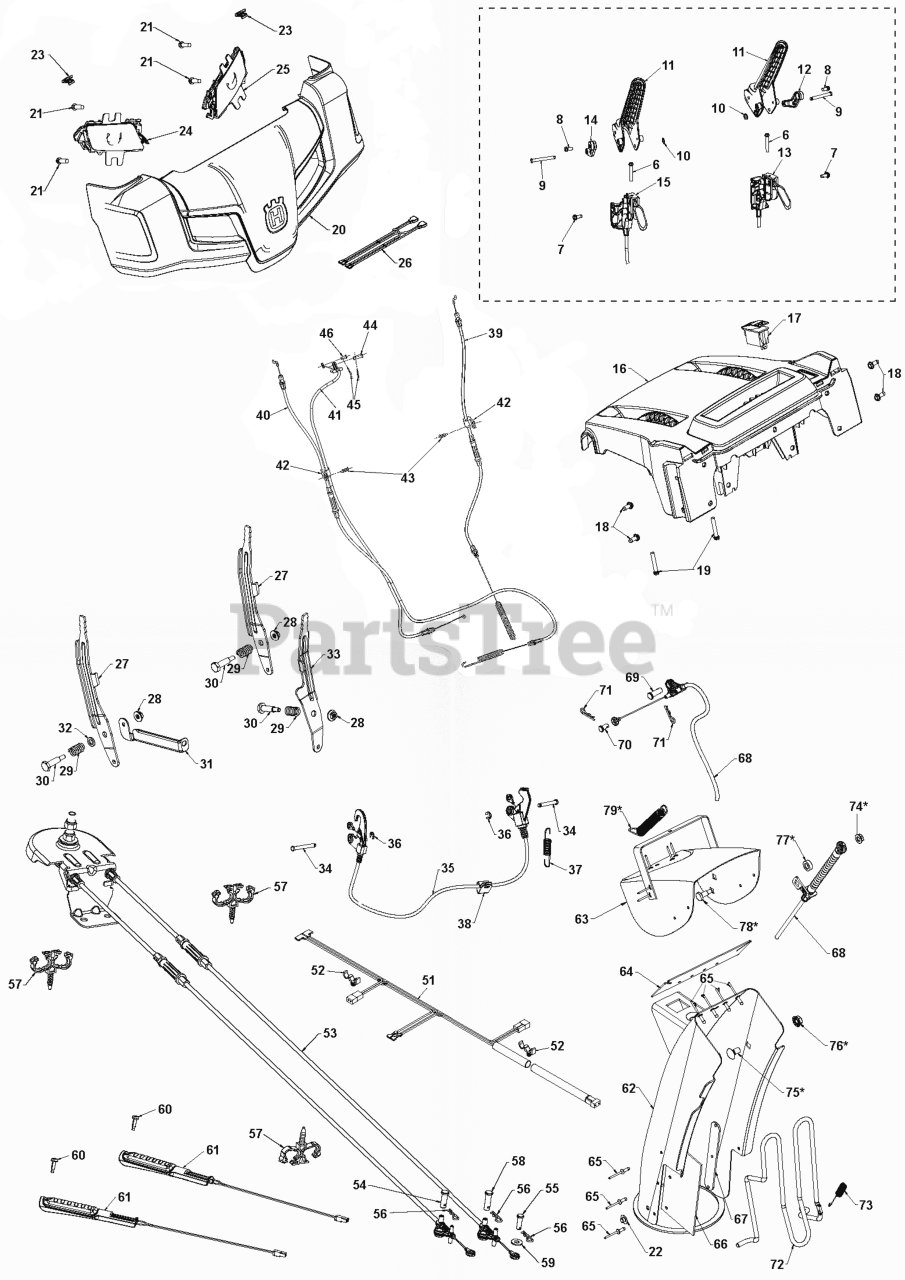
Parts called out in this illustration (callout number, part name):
6	SCREW HEX_WASH_13-16 X 1.50_H
7	SCREW 14-20 X 5/8
8	SCREW.HWH.13-16X.50
9	PIN.GROOVED
11	LEVER CONTROL DSST OPP MPP
12	LEVER.CABLE.ARM.RHS.BLACK
13	CABLE.POWER STEERING.RHS
14	LEVER.CABLE.ARM.LHS.BLACK
15	CABLE.POWER STEERING.LHS
16	CONSOLE.BASE.MULTICONT.498SWIT
17	SWITCH HEATED GRIP BLK
18	SCREW 14-20 X 5/8
19	SCREW HEX_WASH_13-16 X 1.50_H
20	COVER CONSOLE_ASM_HUSQVARNA
21	SCREW.HWH.13-16-5.8.BZP
22	NUT
23	CLIP PANEL ERGO 30603
24	LIGHT ASM.HUSQVARNA.RH
25	LIGHT ASM.HUSQVARNA.LH
26	HARNESS.WIRE.LIGHT.JUMPER
27	LEVER.CONTROL.SPEED/DEFLEC.BLK
28	NUT HEX_LRG FLG_1_4-20_LOCK
29	SPRING.COMPRESSION.82LBS
30	BOLT SHOULDER_HEX HD_1/4-20_3/
31	BRACE.SUPPORT.SPEED.BLACK
32	WASHER.FLAT.625 X .375 NYLON
33	LEVER.CONTROL.CHUTE.ROTATON.BL
34	PIN.GROOVED
35	CABLE INTERLOCK CONTROL ACETAL
37	SPRING RETURN_INTERLOCK_DSST
38	CLIP.CABLE.BLK
39	CABLE.DRIVE CONTROL W/ADJ
40	CABLE.CONTROL.AUGER
41	CABLE.CONTROL.SPEED.DSST.OPP
41	Cables
42	CLIP.CABLE.BLK
43	FASTENER.PUSH.O.250X0.783
44	PIN CLEVIS 5/16X.875
45	HAIRPIN.SOFT.ZINC.059X1.125
46	PIN CLEVIS .25 X .31
51	HARNESS WIRE.LIGHT AND GRIPS
53	CABLE ASSY CONTROL
54	PIN CLEVIS 5/16X.875
55	PIN.CLEVIS
56	HAIRPIN.SOFT.ZINC.059X1.125
57	CLIP.CONDUIT.DOUBLE LOOP
58	PIN CLEVIS CLEVIS
59	WASHER FLAT_.250 X .625 X .06
60	GRIP.HANDLE.HEATED
61	SCREW.PAN.HD.TORX.1/4-20X.750
62	ASM.CHUTE/DEFLECTOR.668
68	CABLE.CONTROL.CHUTE.DEFLEC
68	CABLE CONTROL.CHUTE.DEFLECTOR.
69	PIN CLEVIS 5/16X.875
70	PIN CLEVIS .25 X .31
71	HAIRPIN.SOFT.ZINC.059X1.125
72	ROD.GUARD.CHUTE (2 2)
73	SPRING.CHUTE.GUARD
